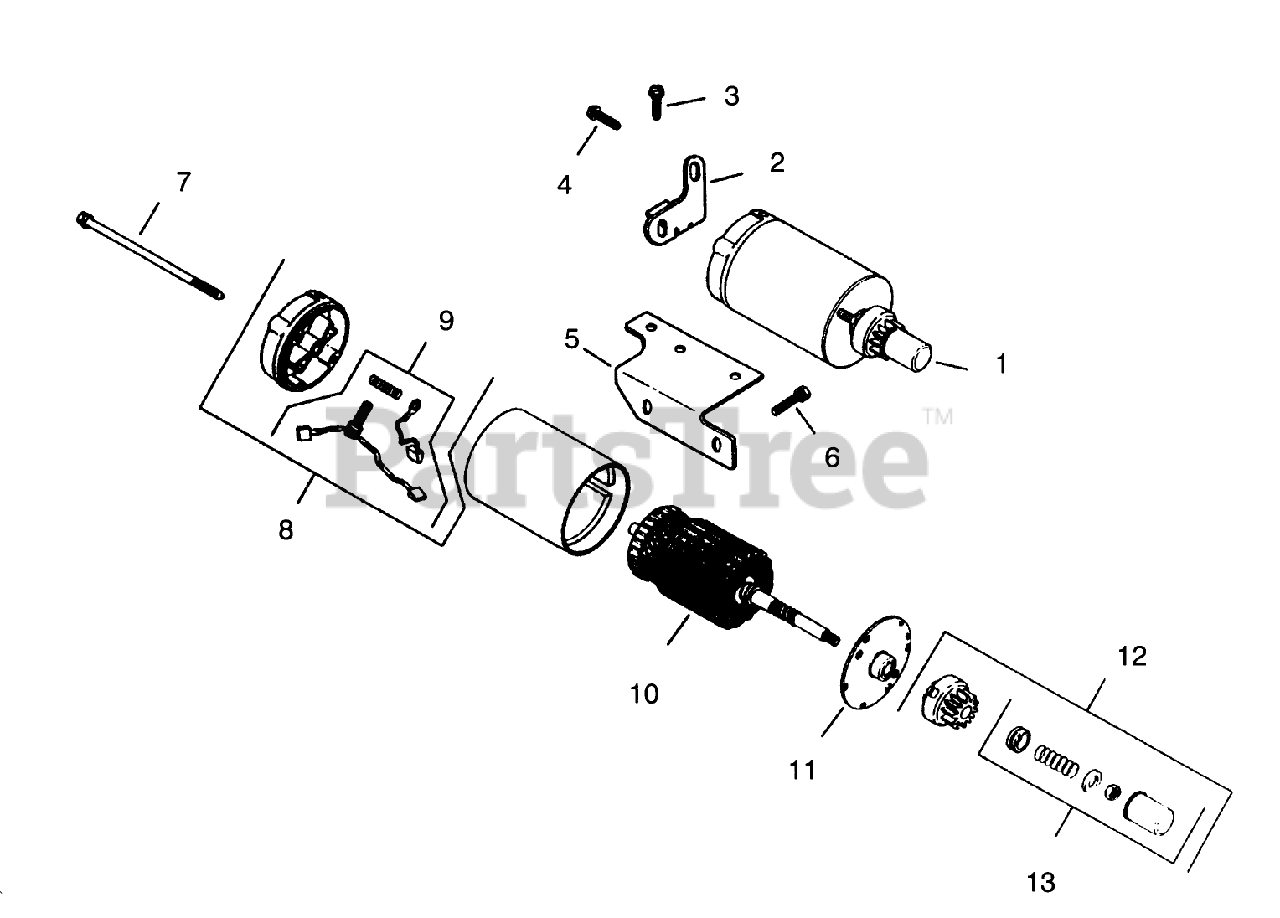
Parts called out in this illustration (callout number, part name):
1	KOHLER 41-098-04
2	KOHLER 45-126-17
3	KOHLER X-67-62
4	KOHLER X-67-83
5	KOHLER 47-126-29
6	KOHLER X-159-2
7	KOHLER 41-086-19
8	KOHLER 41-227-04
9	VNDR #52-755-15
10	KOHLER 47-170-02
11	KOHLER 41-227-03
12	KOHLER 47-755-07
13	KOHLER 47-755-13
